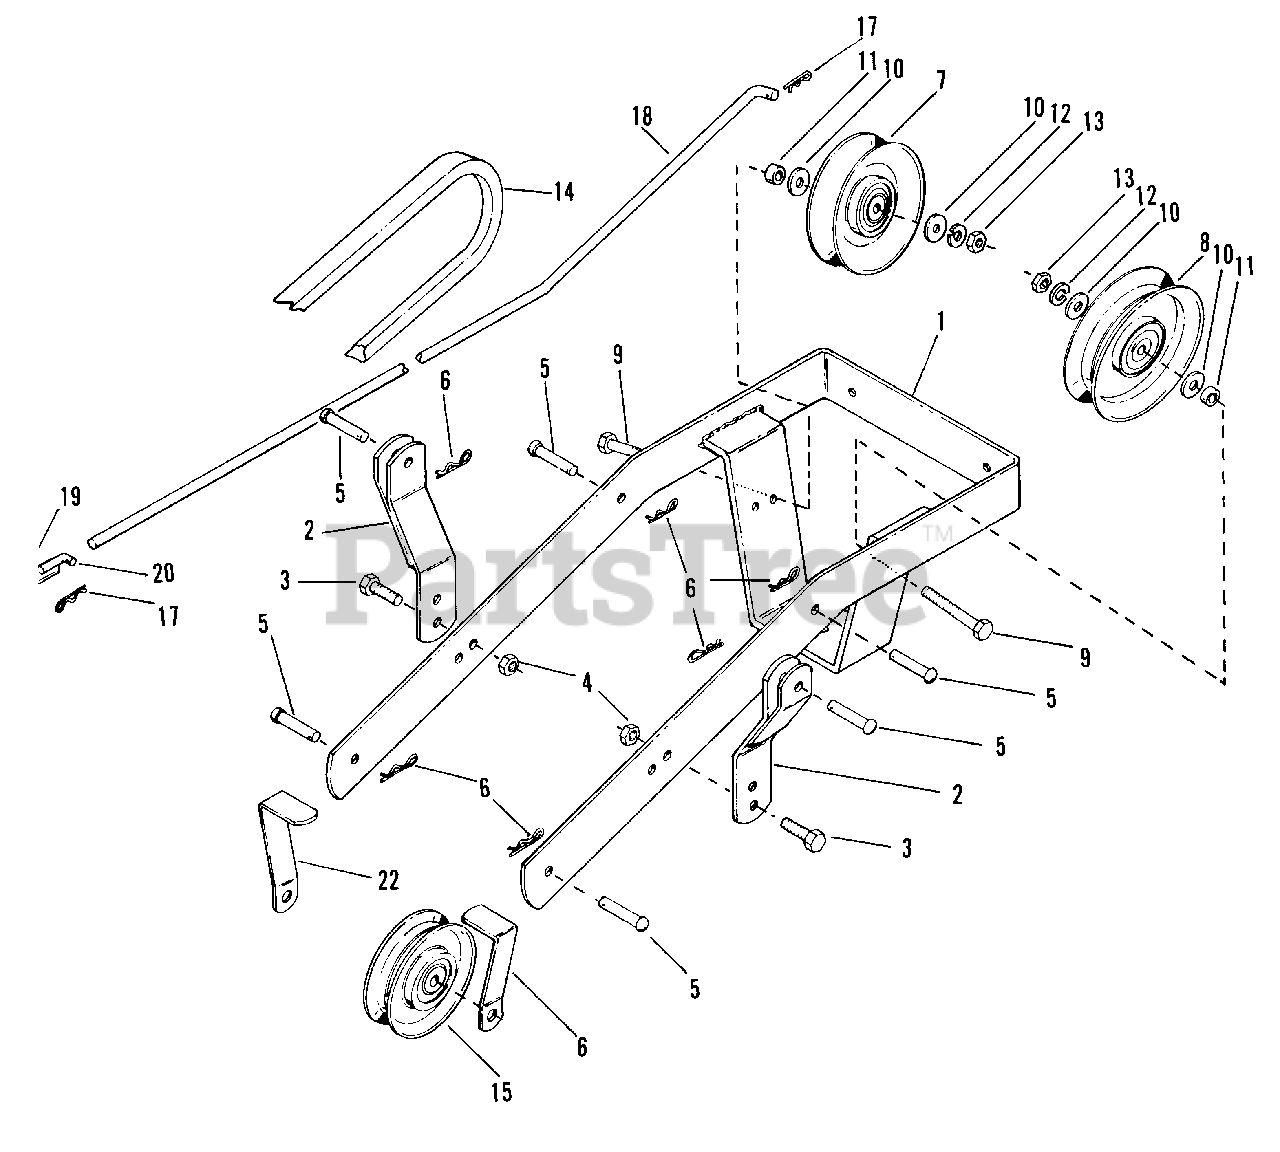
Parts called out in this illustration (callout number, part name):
1	PUSH ARM ASSEMBLY
2	SUPPORT ARM ASSY.
3	CAPSCREW, Hex, Hd., 3/8-16 x 1
4	NUT, Hex, Full Lock, 3/8-16
6	CLIP, Hairpin
8	PULLEY, Idler
9	CAPSCREW, Hex, Hd., 3/8-16 x 1-3/4
10	WASHER, Plain, 5/16
12	LOCKWASHER, 3/8
13	NUT, hex, 3/8-16 x 2
14	BELT, "V", Drive
15	PULLEY, Idler
16	STOP, Belt
17	CLIP, Hairpin
18	ROD, Lift
19	SCREW, Set, Sq. Hd., 5/16-18 x 3/8
20	ROD GUIDE ASSY.
21	DECAL, Safety
22	STOP, Belt
